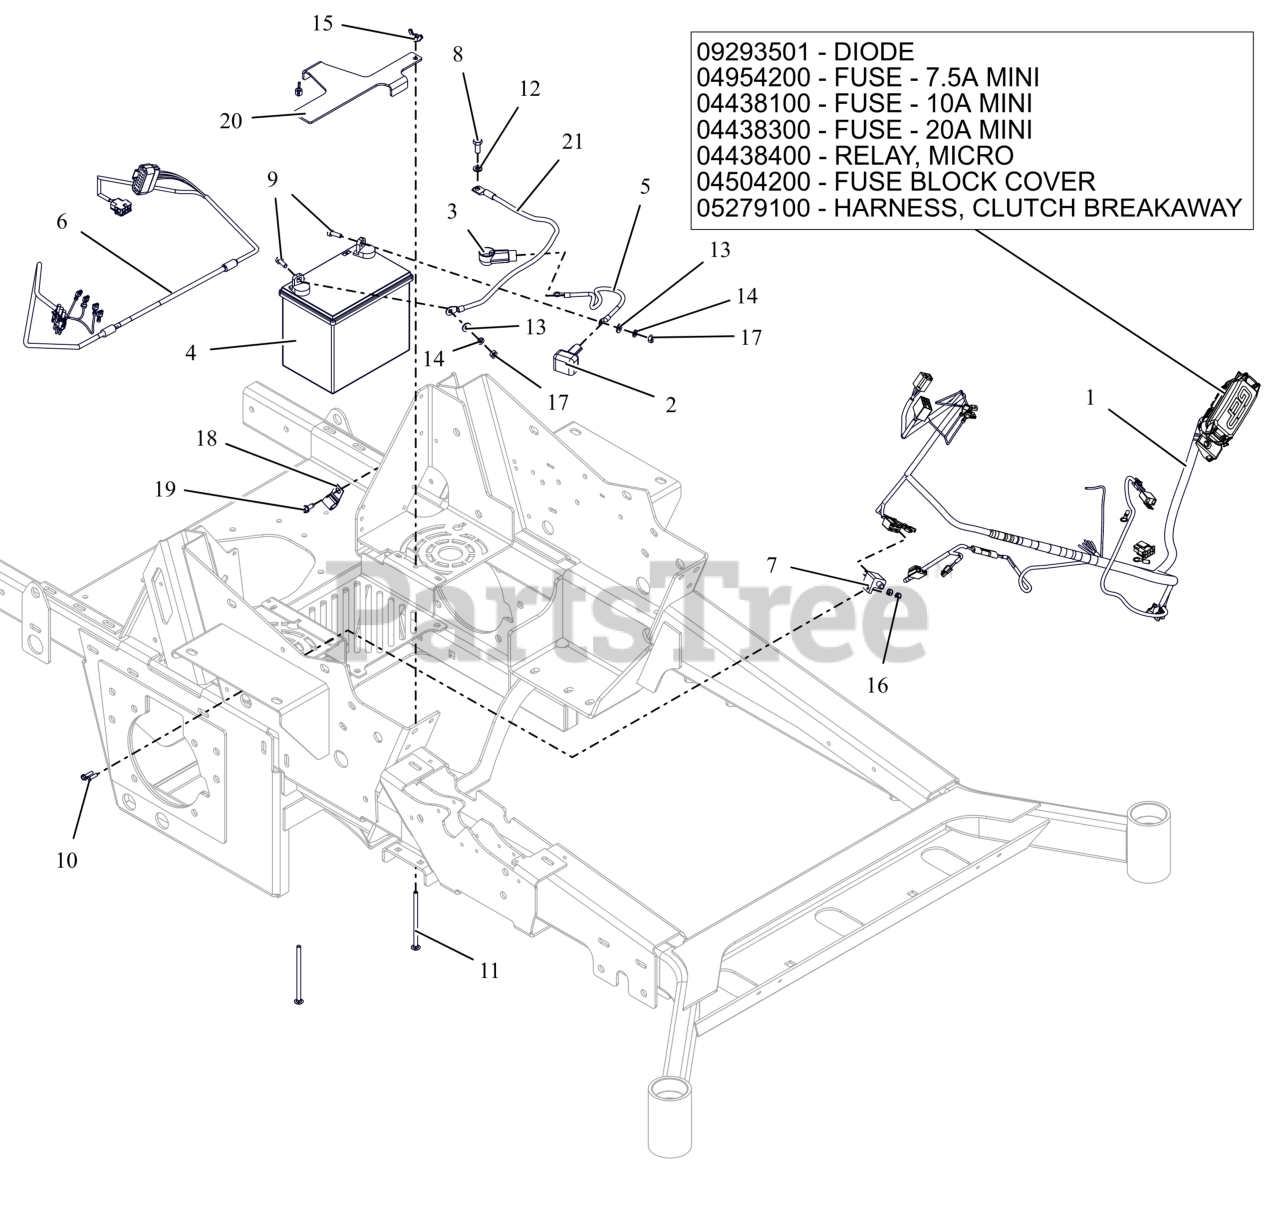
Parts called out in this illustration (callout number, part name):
1	HARNESS- WIRE PT300 MAIN
1	DIODE, CONNECTOR SHELL
1	FUSE, 7.5 AMP MINI-ATC
1	FUSE,10 AMP MINI-ATC
1	FUSE,20 AMP MINI ATC
1	RELAY,MICRO5 TERML W/RESISTOR
1	COVER, HARNESS FUSE/RELAY MOD
1	HARNESS, CLUTCH BREAKAWAY
2	INSULATOR
3	BOOT, .65ID POS
4	BATTERY, 300 CCA 10U1L
5	CABLE, STARTER 13.00"
6	HARNESS- EFI ENG ADAPTER PT300
7	SWITCH- DOUBLE POLE N.O./N.O.
8	BLT, HEX M8-1.25X20 G8.8 ZCC
9	BLT, HEX .25-20X.75 G5 ZCC
10	BLT, HWH #10-24X.75 ZCC
11	BLT, RHSN .25-20X4.50 G5 ZCC
12	WSHR,LK-REG .312X.078 ZCC
13	WSHR,FLT .281X.625X.065 ZCC
14	WSHR,LK-REG .250X.062 ZCC
15	NUT, LK-WING .25-20 ZCC
16	NUT-LK-NYL #10-24 G2 ZCC
17	NUT-STD .250-20 G2 ZCC
19	SCR,TAP .25-20X.625 HWH ZCC
20	HOLDDOWN- BATTERY
21	CABLE- NEG 16.00 IN
